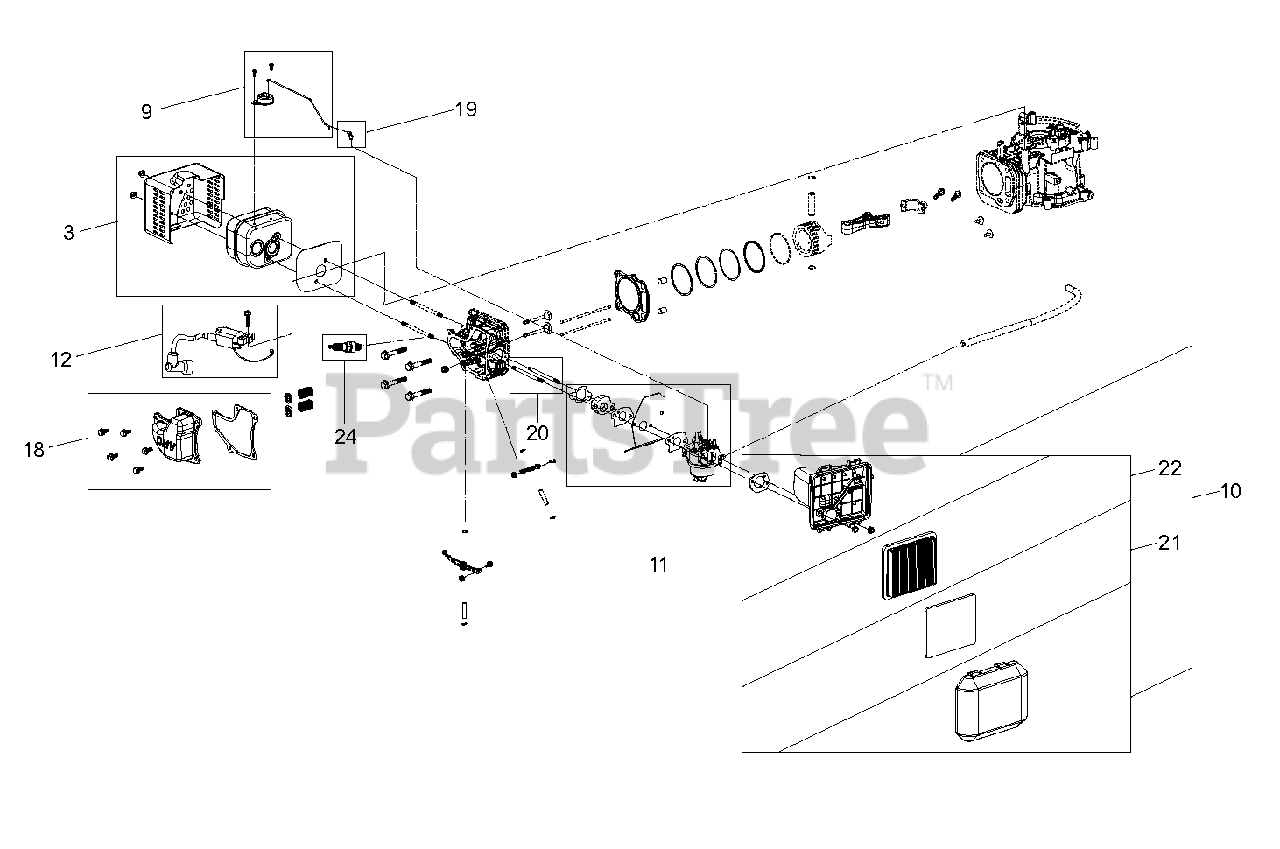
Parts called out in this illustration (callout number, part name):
1	AIR VANE CHOKE KIT
2	GOVERNOR ARM KIT
3	MUFFLER AND SHIELD KIT
4	FLYWHEEL AND FAN KIT – RECOIL START
5	KIT BRAKE ASSEMBLY RECOIL
7	KIT ARIENS STYLE
8	KIT FLYWHEEL SHIELD
9	THERMAL CHOKE CONTROL KIT
10	KIT-AIR CLEANER ASM, 2 HINGE
11	CARBURETOR COMPLETE KIT
12	IGNITION COIL KIT
18	KIT-VALVE COVER (1P65FA)
19	LOCK-THROTTLE
20	STUD-INTAKE
21	AIR FILTER, FOAM PRE-FILTER
22	AIR FILTER ELEMENT
23	FUEL LINE WITH STRAINER
24	SPARK PLUG
25	OIL FILTER TUBE/CAP
26	GAS CAP WITH CANISTER
27	FUEL TANK
28	RECOIL ASSEMBLY
